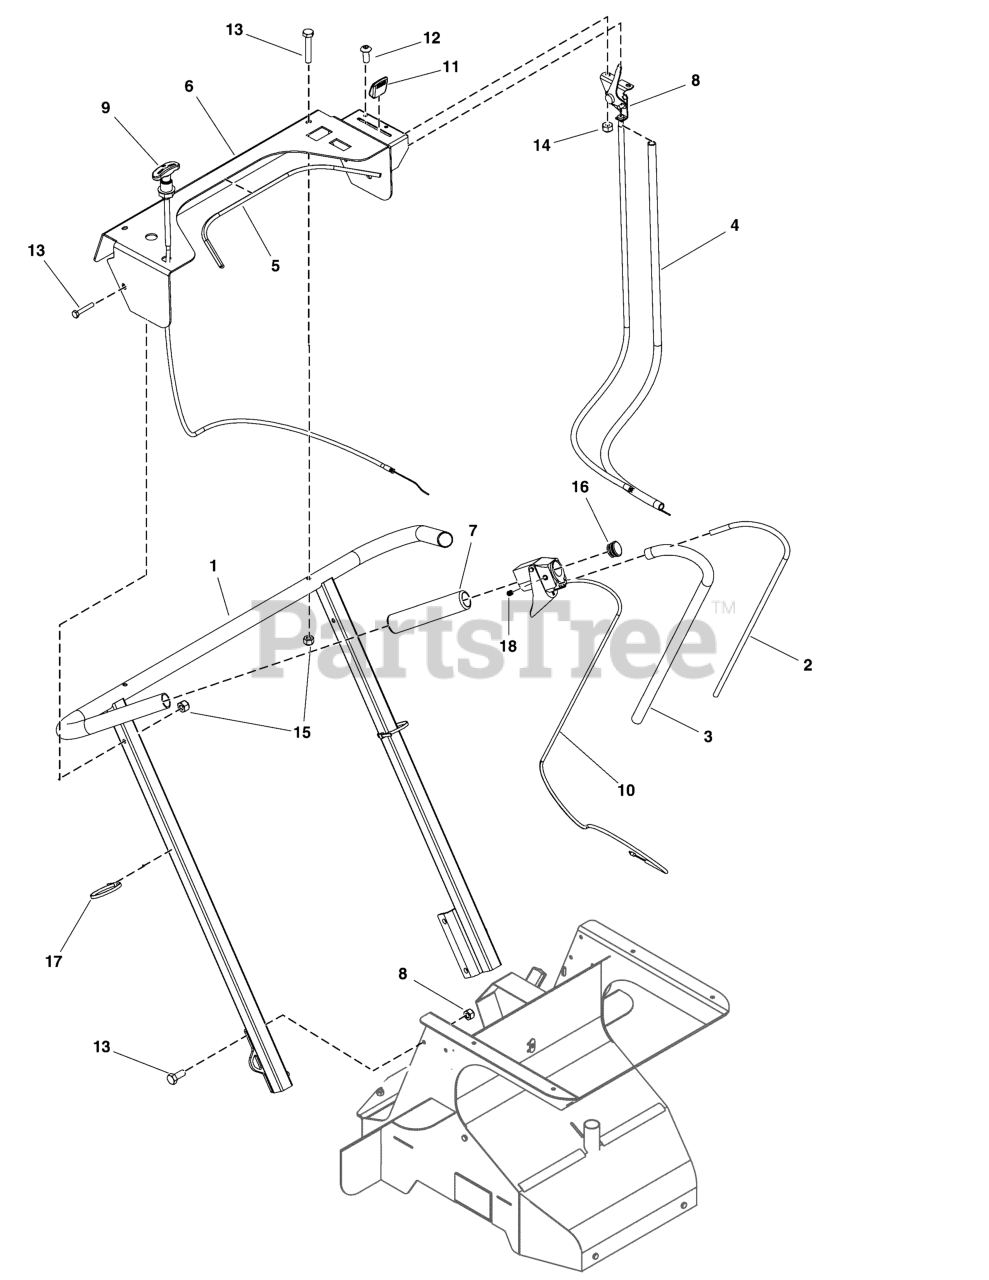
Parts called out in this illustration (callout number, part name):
1	WELD, HANDLE BAR ROVER
2	ROD,CABLE SUPPORT
3	THROTTLE CABLE SPLIT LOOM, .500" ID
4	SPLIT LOOM, GATE CABLE, 28"
5	TRIM, U-CHANNEL 15.8125" LONG
6	PLATE,CONSOLE ROVER (SANDED)
7	GRIP, .94 ID X .155 THK X 5.75 LONG
8	CABLE, LEVER ACTION 34"
9	CABLE, TURN TO LOCK, 35"
10	KIT, ROVER/PATHFINDER THROTTLE CABLE
11	KNOB, GATE LEVER
12	SCR-CAP, BSH #10-24 X .500" SS188
13	SCR-CAP, HEX .250"-20 X 1.500" SSF593C
14	NUT-HEX-NYLK, #10-24 SS188
15	NUT-HEX-NYLK, .250"-20 SS188
16	PLUG, 1" TUBE, ROUND
17	CABLE TIE, .188" W X 7.50" LNG
18	SCR-SH, SET .3125"-18 X .375" KCPT SS188
